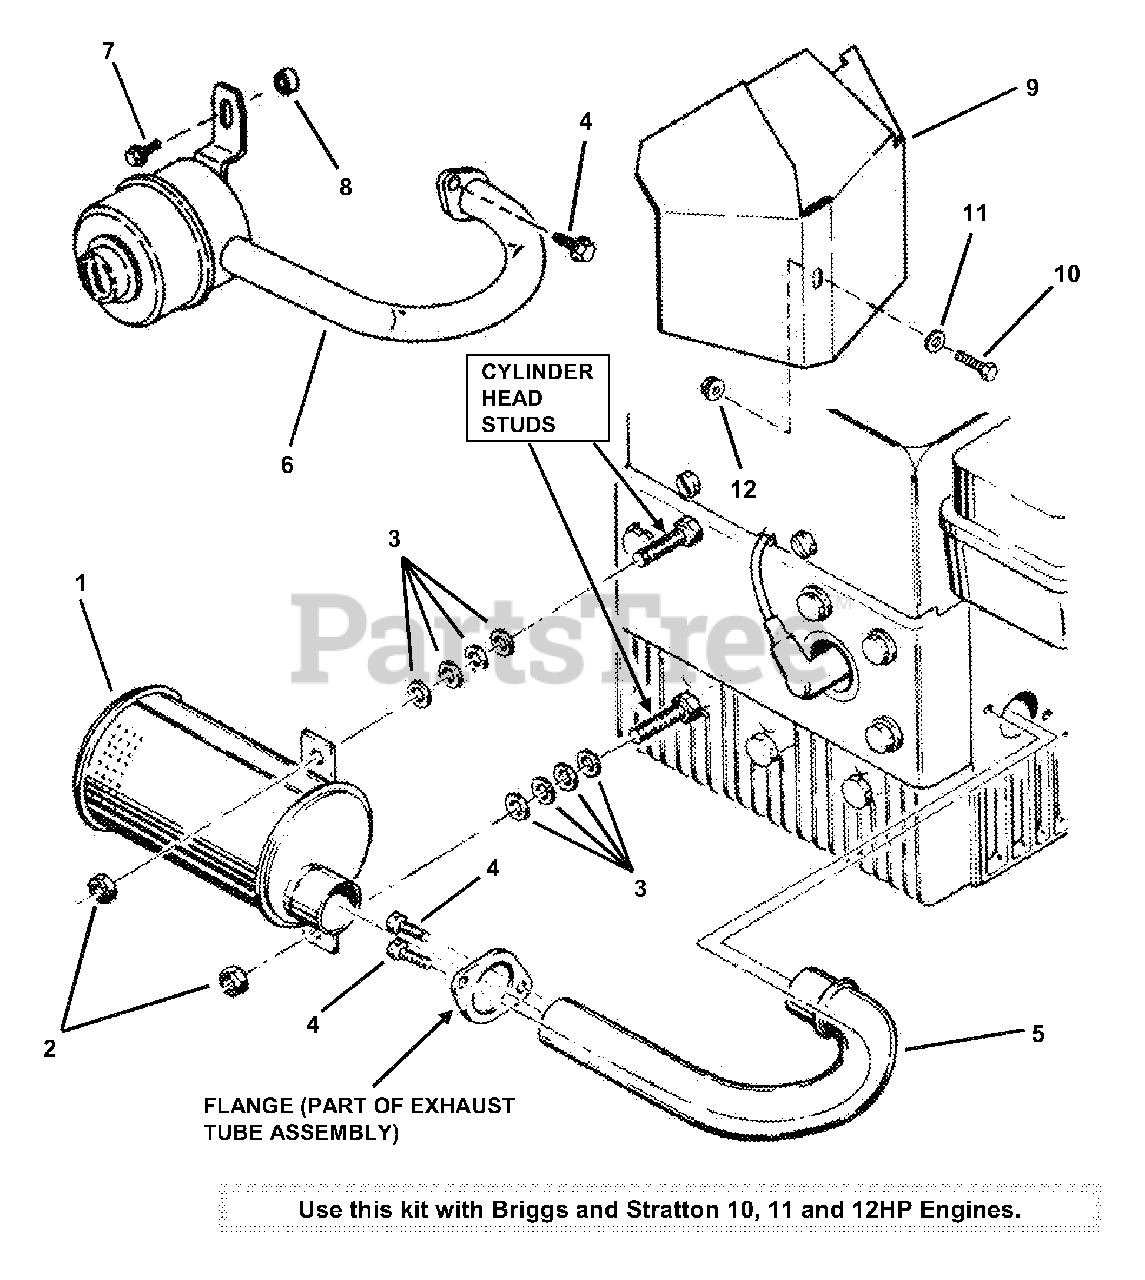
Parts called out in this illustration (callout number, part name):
1	MUFFLER, 11HP Briggs
2	NUT, 5/16-18 Hex
3	WASHER, 5/16 Flat
4	SCREW, 5/16-18 x 3/4" Hex Head Cap
5	TUBE, Exhaust
6	MUFFLER, 10 & 12HP Briggs
7	SCREW, 1/4-20 x 3/4" Hex Head Cap
8	SPACER (10HP Models)
9	HEAT SHIELD, 11HP Briggs
10	SCREW, 1/4-28 x 1-1/2" Hex Head Cap
11	WASHER, 1/4" Flat
12	NUT, 1/4-28 Hex Flange Lock
